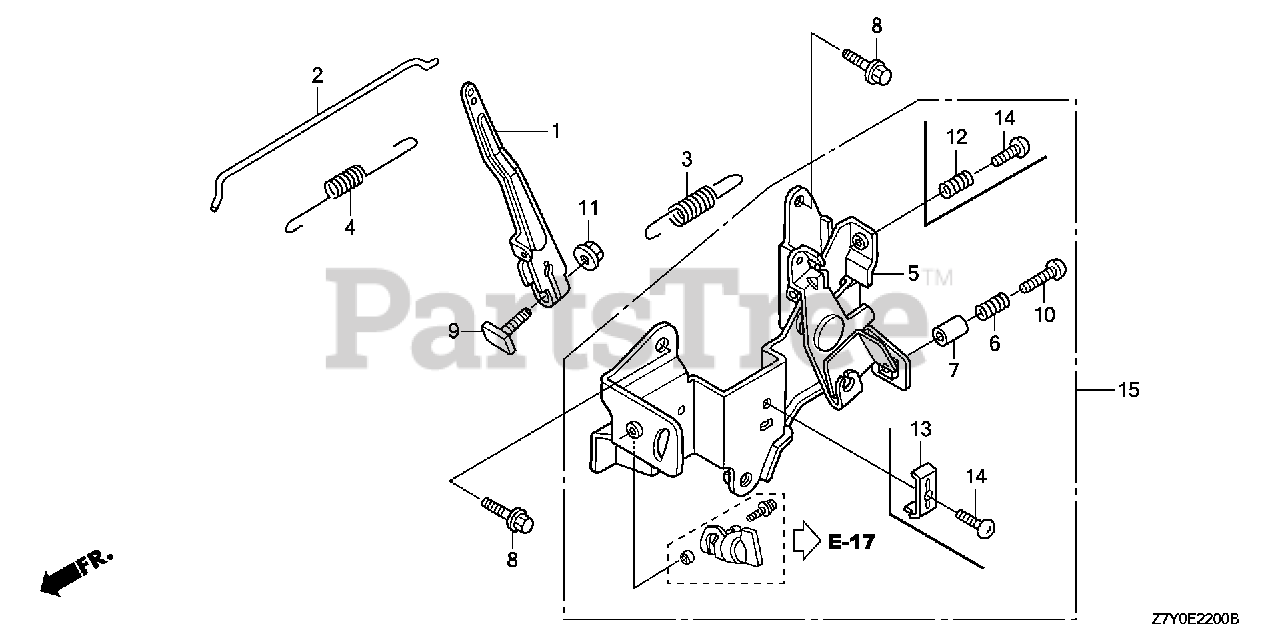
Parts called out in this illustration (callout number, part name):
1	ARM, GOVERNOR
2	ROD, GOVERNOR
3	SPRING, GOVERNOR
4	SPRING, THROTTLE RETURN
5	BASE, CONTROL
6	SPRING, CONTROL ADJUSTING
7	COLLAR, STOPPER
8	BOLT, FLANGE (5X12)
9	BOLT, GOVERNOR ARM
10	SCREW, RECESSED (5X28)
11	NUT, FLANGE (6MM)
15	CONTROL ASSY.
